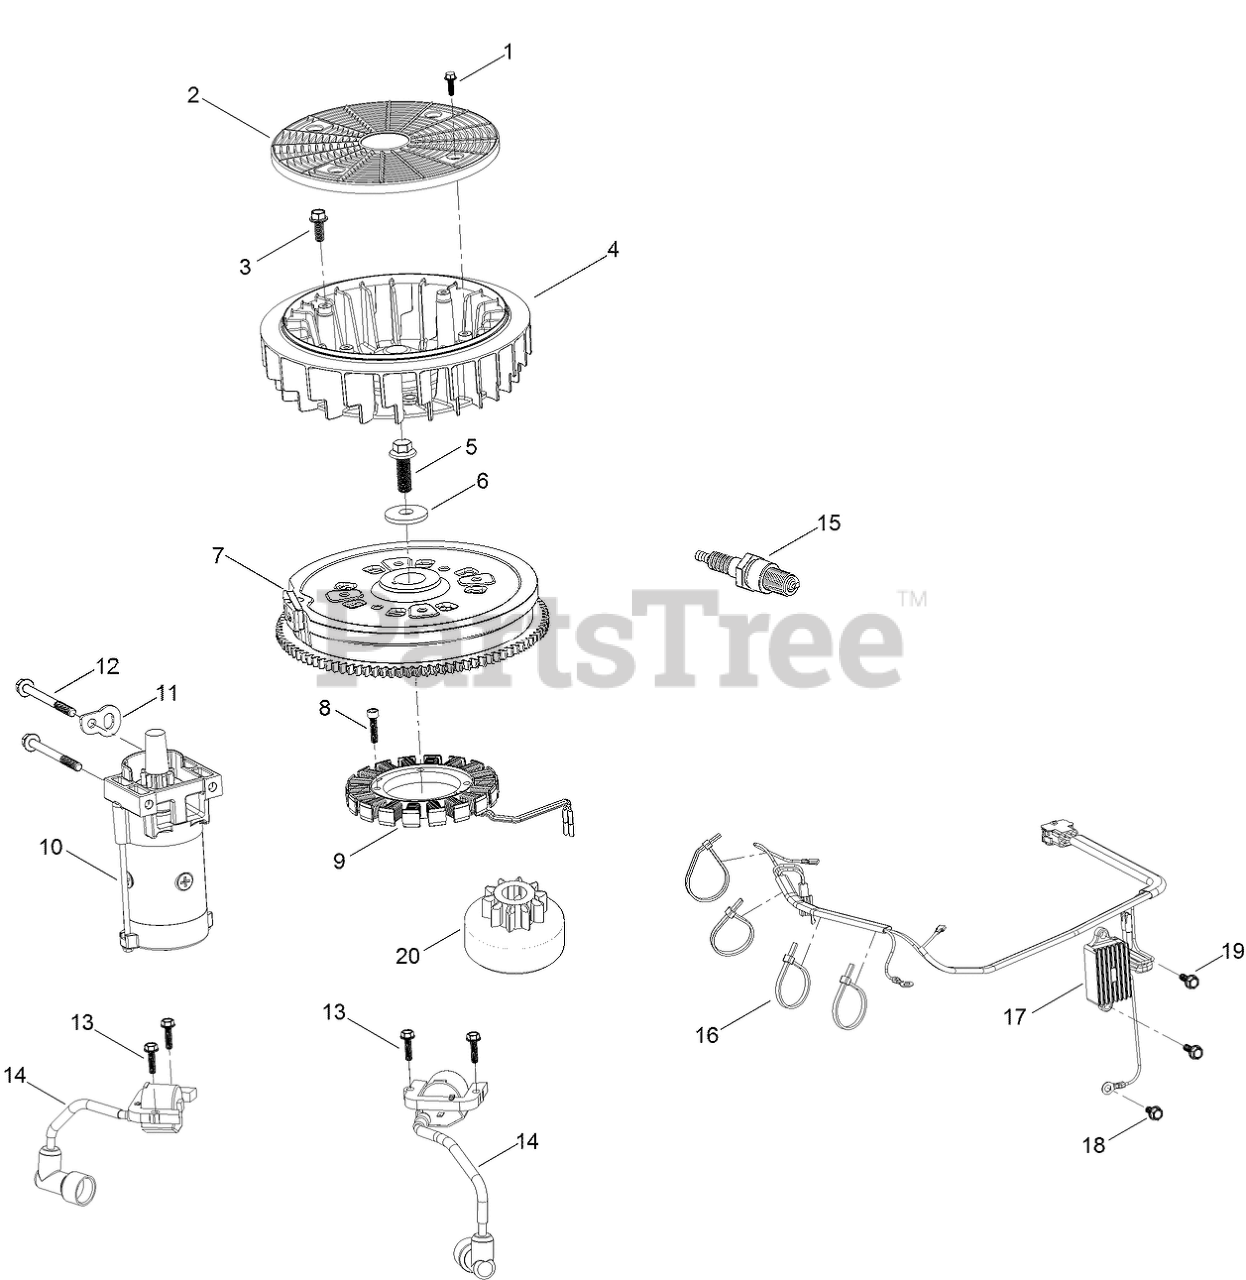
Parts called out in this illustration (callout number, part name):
1	SCREW-HWH
2	SCREEN-ROTATING
3	SCREW-HWH
4	FAN-COOLING
5	SCREW-HWH
6	WASHER-FLAT
7	FLYWHEEL
8	SCREW-HSH
9	ALTERNATOR
10	MOTOR-STARTER
11	BRACKET-LIFT
12	SCREW-HHF
13	BOLT-FLANGE
14	IGNITION COIL ASM
15	SPARK PLUG
16	TIE-ZIP
17	REGULATOR-VOLTAGE W/HARNESS
18	SCREW-HHF
19	SCREW-HHF
20	PINION-STARTER
